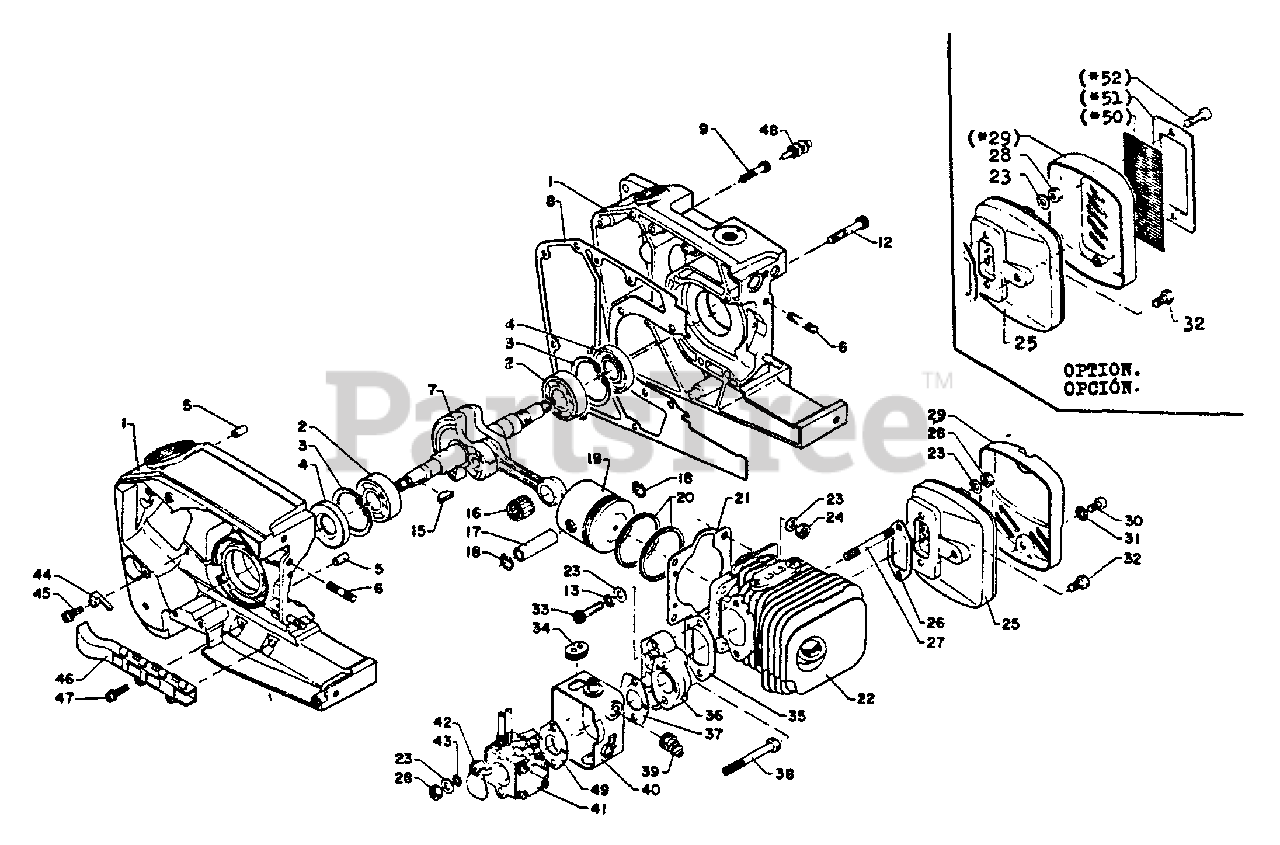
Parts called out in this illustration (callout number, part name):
1	CRANKCASE KIT
2	BEARING, BALL - 6202
3	RING, RETAINING - 35
4	SEAL, OIL
5	PIN - LOCATING
6	STUD
7	CRANKSHAFT ASSY
8	GASKET, CRANKCASE
9	SCREW - 4X20
12	SCREW - 5X30
13	LOCKWASHER - 5
16	BEARING, NEEDLE
17	PIN, PISTON
18	RING, RETAINING - 8
19	PISTON
20	RING, PISTON
21	GASKET, CYLINDER
22	CYLINDER
23	WASHER - 5
25	MUFFLER ASSY
26	GASKET, EXHAUST
28	LOCKNUT - 5
29	LID, MUFFLER
29	COVER, MUFFLER
30	SCREW - 5X16
31	LOCKWASHER - 5
32	BOLT - 5X10
33	SCREW - 5X20
34	GROMMET
35	GASKET, INTAKE
36	CASE, CARBURETOR
37	GASKET, INTAKE
39	GROMMET
40	CASE, CARBURETOR
41	CARBURETOR WA-38
42	SHUTTER, CHOKE
43	WASHER - 5
45	SCREW - 4X10
46	CLAMP
47	SCREW - 4X14
48	SEAL, DUST
49	GASKET, INTAKE
50	SCREEN, SPARK ARRESTOR
51	RETAINER, SCREEN
52	SCREW - 5X16
